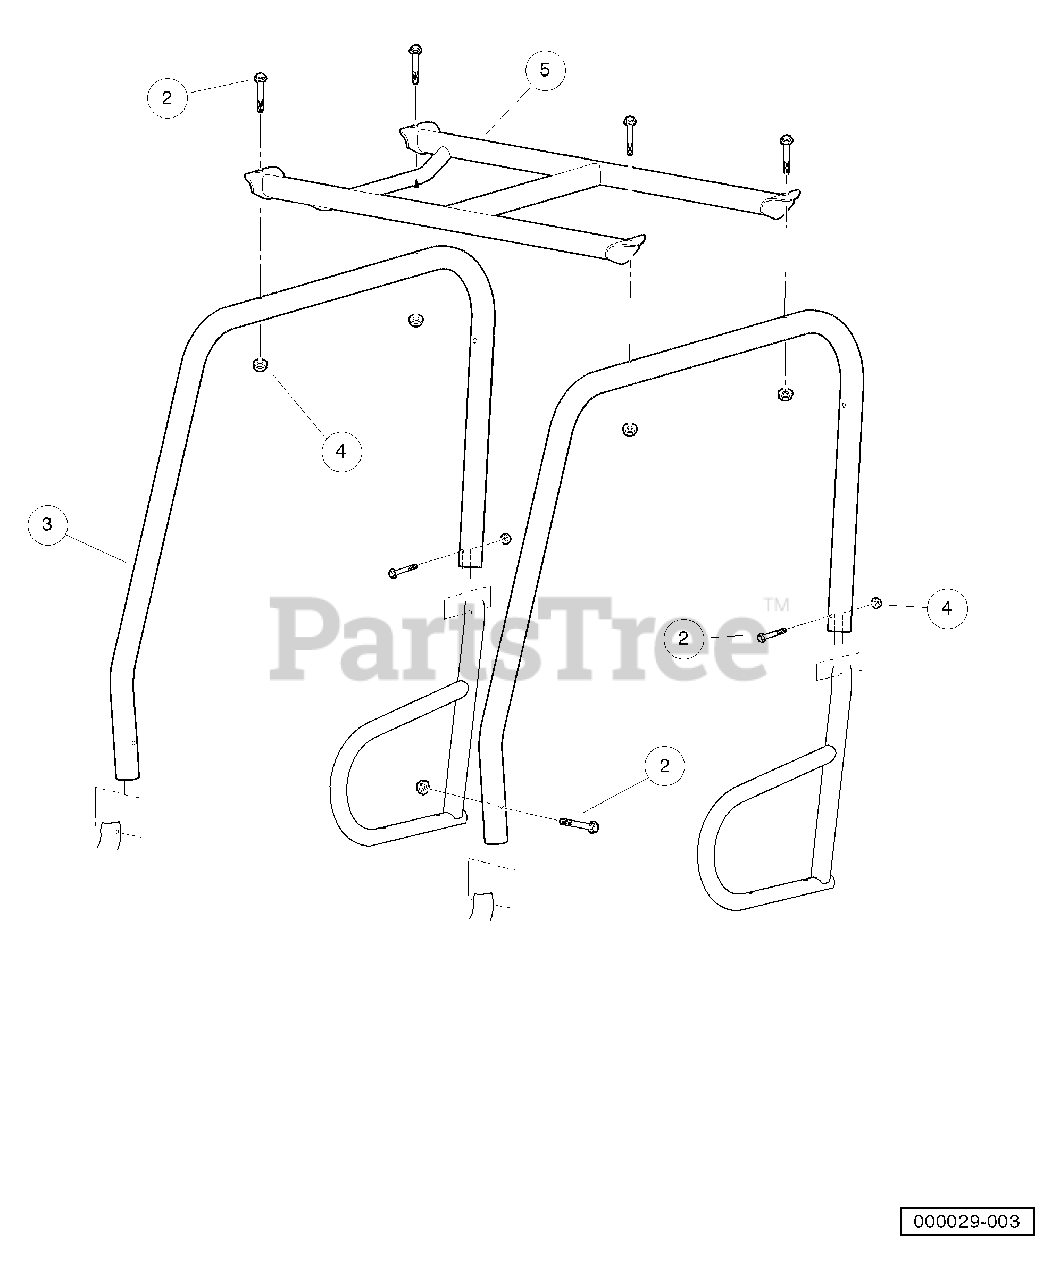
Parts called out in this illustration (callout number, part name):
1	Kit, ROPS, Domestic
2	Bolt, Flanged, M10 X 1.5 X 65
3	Tube, Side Support Short, ROPS
4	Nut, Flanged, M10 x 1.5, Black
5	Asm, Top, ROPS
